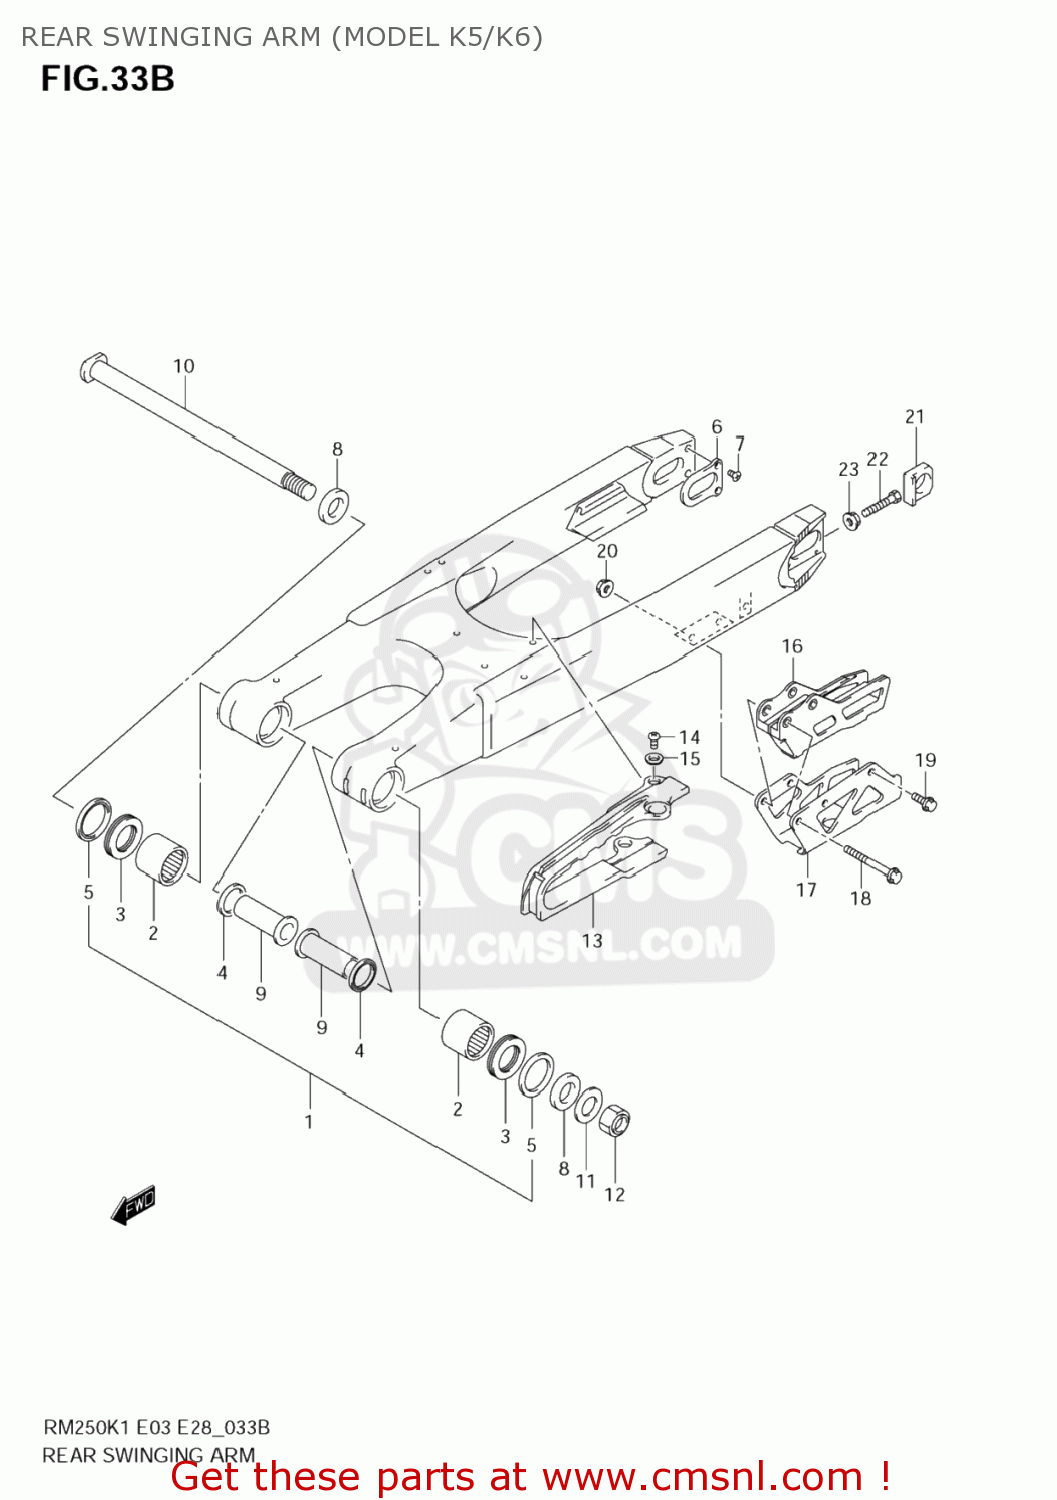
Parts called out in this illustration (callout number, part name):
1	SWINGINGARM ASSY,RR
2	BEARING(22X29X30)
3	BEARING(22X35X2)
4	SEAL,OIL(22X29X4)
5	SEAL,RR SWGARM PIVOT OUTER
6	PLATE,RR SWING ARM RR
7	SCREW,UPPER
8	SPACER,RR SWGARM PIVOT OUTER
9	SPACER,SWGARM PIVOT INNER
10	SHAFT,RR SWINGINGARM PIVOT
11	WASHER, FIXED DRIVE FACE
12	NUT
13	BUFFER,CHAIN TOUCH DEFENSE
14	SCREW
15	WASHER
16	GUIDE,CHAIN
17	PLATE,CHAIN GUIDE
18	BOLT(6X45)
19	BOLT(6X12)
20	NUT
21	WASHER,CHAIN ADJUSTER
22	BOLT(8X50)
23	NUT
